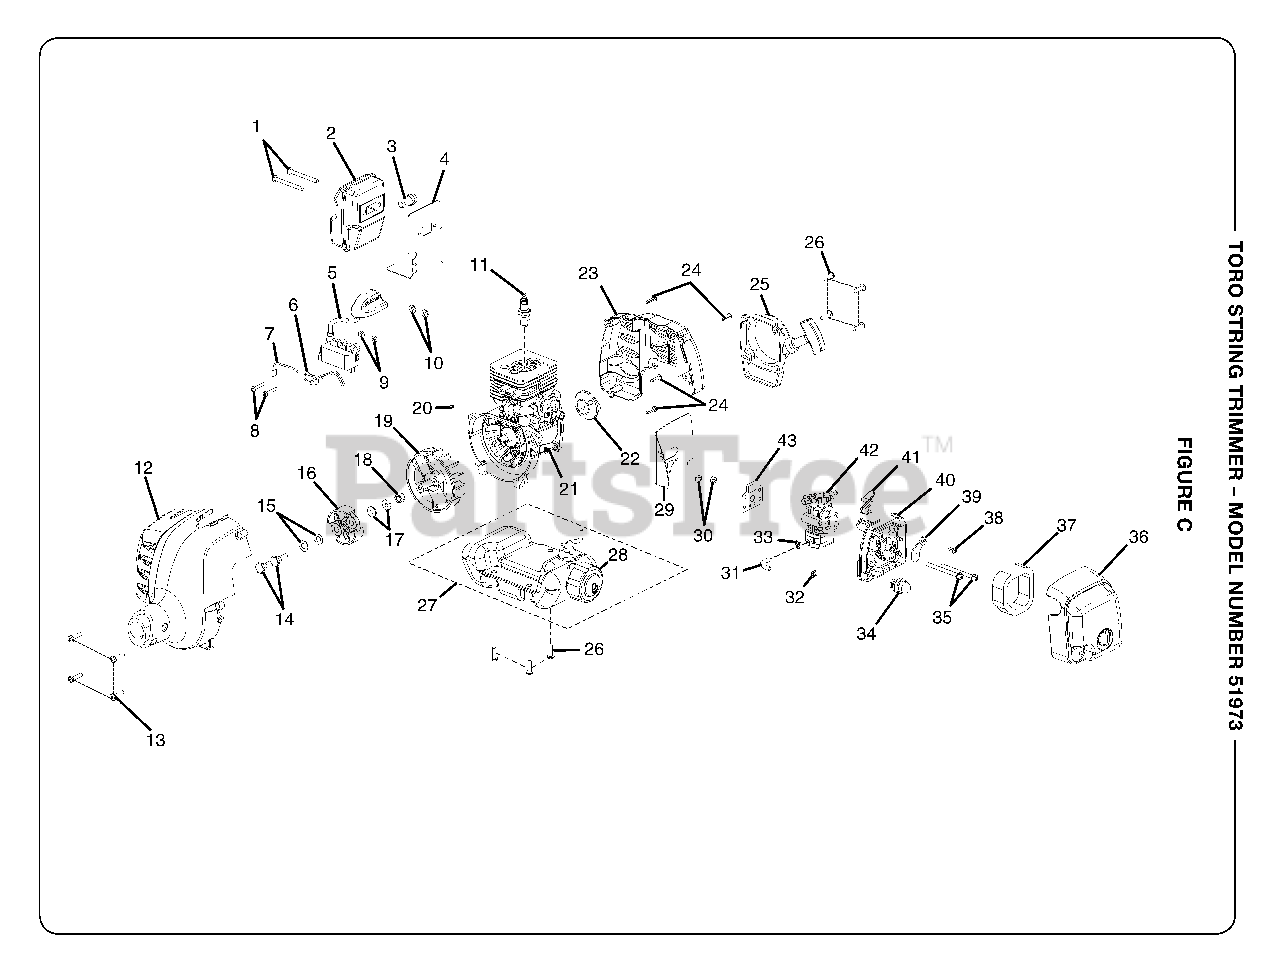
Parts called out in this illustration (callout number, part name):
1	SCREW (M5 X 50 mm TORX SLOTTED RECESSED PAN HD.)
2	MUFFLER ASSEMBLY
4	MUFFLER GASKET
5	COIL BOOT ASSEMBLY
6	LEAD ASSEMBLY, RED
7	LEAD ASSEMBLY, BLACK
8	SCREW (M4 X 22 mm Torx SLOTTED RECESSED PAN HD.)
11	SPARK PLUG
12	FRONT HOUSING ASSEMBLY
13	SCREW (M5 X 20 mm Torx SLOTTED RECESSED PAN HD.)
14	CLUTCH SCREW
15	CURVED WASHER
16	CLUTCH ASSEMBLY
17	WASHER
18	ROTOR NUT
19	ROTOR
20	WOODRUFF KEY (10 mm X 3 mm)
21	SHORT BLOCK ASSEMBLY
22	PULLEY ASSEMBLY
23	ENGINE HOUSING, REAR
24	SCREW (M4 X 16 mm Torx RECESSED PAN HD.)
25	STARTER RECOIL ASSEMBLY
26	SCREW (M5 X 16 mm Torx SLOTTED)
27	FUEL TANK ASSEMBLY
28	FUEL CAP ASSEMBLY
29	INSULATOR GASKET
30	NUT (M5 X .8 mm)
31	FUEL LINE
32	HOSE CLIP
33	HOSE CLIP
34	PRIMER ASSEMBLY
35	SCREW (M5 X 60 mm SLOTTED RECESSED PAN HD.MACHINE)
36	COVER ASSEMBLY
37	ELEMENT
38	SCREW (M4 X 12 mm SLOTTED RECESSED PAN HD.)
39	CHOKE PLATE
40	CARBURETOR PLATE
41	CHOKE LEVER
42	CARBURETOR ASSEMBLY
43	CARBURETOR GASKET
